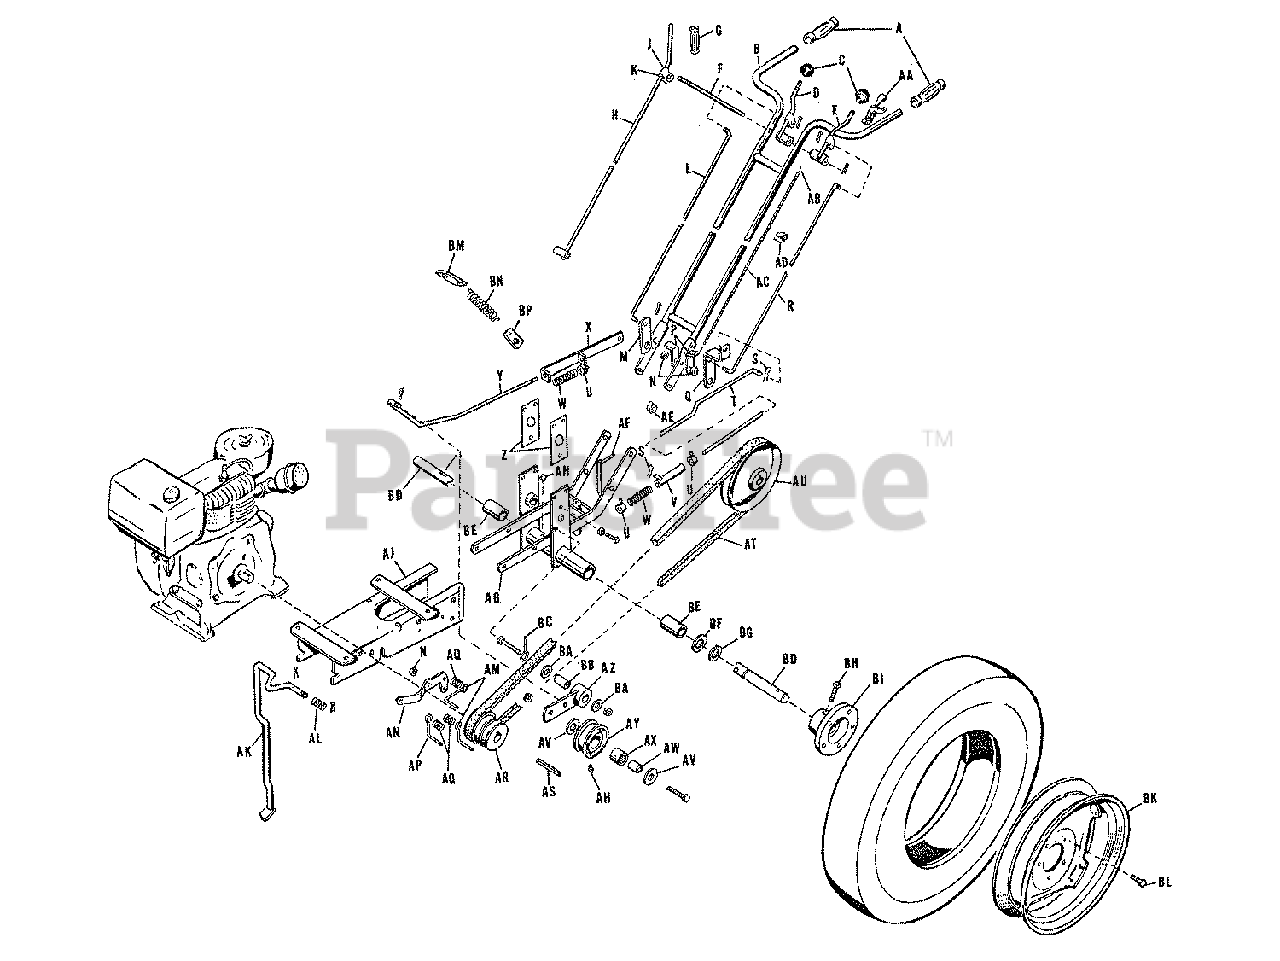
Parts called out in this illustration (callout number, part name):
A	GRIP, Handle
B	HANDLE ASSEMBLY
C	BALL, Clutch Lever
D	LEVER ASSEMBLY, Clutch, R.H.
E	LEVER ASSEMBLY, Clutch, L.H.
F	SHAFT, Lever
H	ROD ASSEMBLY, Shift
J	GUIDE, Rod
K	LINER (Nylon)
L	ROD, Upper Idler
M	LEVER, Pivot
P	STOP, Lever
Q	LEVER, Lower Clutch
R	ROD, Clutch
S	CLIP, Spring
T	ROD, Lower Clutch
U	COLLAR, Set
V	SOCKET ASSEMBLY, Rod
W	SPRING, Idler Rod
X	GUIDE ASSEMBLY, Idler Clutch Rod
Y	ROD, Clutch, Lower Idler
Z	GASKET, Transmission Case Support
AA	CONTROL, Throttle Lever
AB	WIRE, Throttle
AC	CABLE, Throttle
AD	CLIP, Cable
AE	CLAMP, Cable
AF	PIN ASSEMBLY, Hitch
AG	FRAME ASSEMBLY
AH	FITTING, Grease, Alemite #1641
AJ	BASE ASSEMBLY
AK	STAND ASSEMBLY
AL	SPRING, Stand
AM	STOP, Belt
AN	HOLDER, Belt Stop
AR	PULLEY, Engine
AS	KEY, Engine Pulley
AT	BELT, Drive, 45" Super Combine
AU	PULLEY, Transmission
AV	WASHER, Thrust
AW	RACE, Inner Bearing
AX	BEARING, Idler Pulley
AY	PULLEY, Idler
AZ	LEVER, Idler Assembly
BA	WASHER, Plain, 3/8"
BB	SPACER, Idler Lever
BC	PIN, Lock
BE	BEARING, Axle
BG	RING, Retaining
BH	SCREW, Square Head, Set, 3/8-16 x 1-1/4"
BJ	HUB, Wheel, L.H.
BK	WHEEL, Drive (Specifiy Color)
BM	HOLDER, Spring, Upper
BP	HOLDER, Spring, Lower
